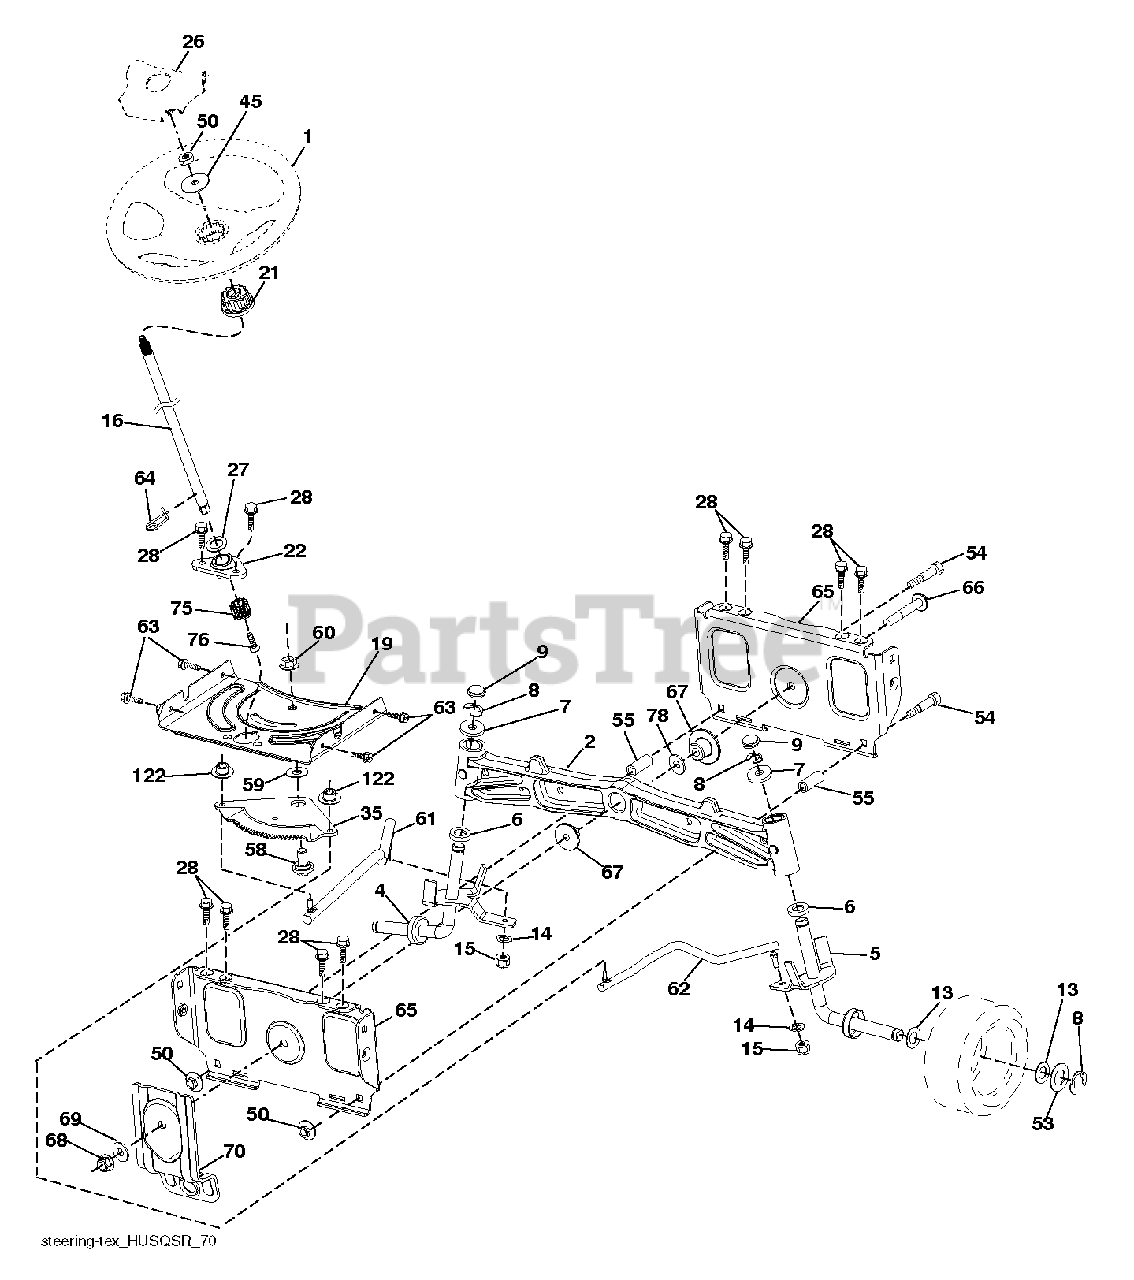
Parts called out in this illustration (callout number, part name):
1	WHEEL.STEER.HUSQ.SR.498.OVMLD
2	AXLE.CAST.IRON
4	SPINDLE.WELDED.LH.16"TEX
5	SPINDLE.WELDED.RH.16"TEX
6	THRUST WASHER
9	CAP.SPINDLE.BLACK
14	SLW 3/8 STD
15	NUT CROWNLOCK 3/8-24
16	SHAFT.STEER.2HIGH.SPLND.PLATED
19	PLATE.STEER.DDL.NLT/NG
21	ADAPTER.WHEEL.STEER.SPLND.ALUM
22	BEARING.SUBASM.SHAFT.STEER.LOW
26	INSERT.CAP.WHL.STRG.HUSQ.PREM
28	SCREW, 3/8-16X3/4
35	GEAR.SECTOR.PLATE.DDL.
45	WASHER.3/8ID.2-3/8OD.12GA.PLTD
50	NUT LOCK FLG 3/8-16 UNC
53	WASHER.HARDENED
55	SPACER.BRACE.AXLE
58	BOLT.SHOULDER.SECTOR.P
59	WASHER.THURST.SECTOR.S
60	NUT FLANGE LOCK 5/8-11
61	LINK.ASM.DRAG.ADJUST.LH.PLATED
62	LINK.ASM.DRAG.ADJUST.RH.PLATED
63	SCREW
64	RETAINER.CLIP.SPRING.S
65	BRACE.AXLE.FRONT.NLT/N
66	BOLT HEX FGHD 7/16-14 X 3 SERR
67	BUSHING.PM.FRONT AXLE
68	NUT.LOCK.FLANGE.7/16
69	WASHER.1.5X.505X.118
70	BRACKET.FRT.DECK.SUSP.RR.MT431
75	PINION.ZINC PLATED
76	SCREW HEAD SOCKET LRVB
78	THRUST WASHER
122	CAP.GEAR.SECTOR.TEX
